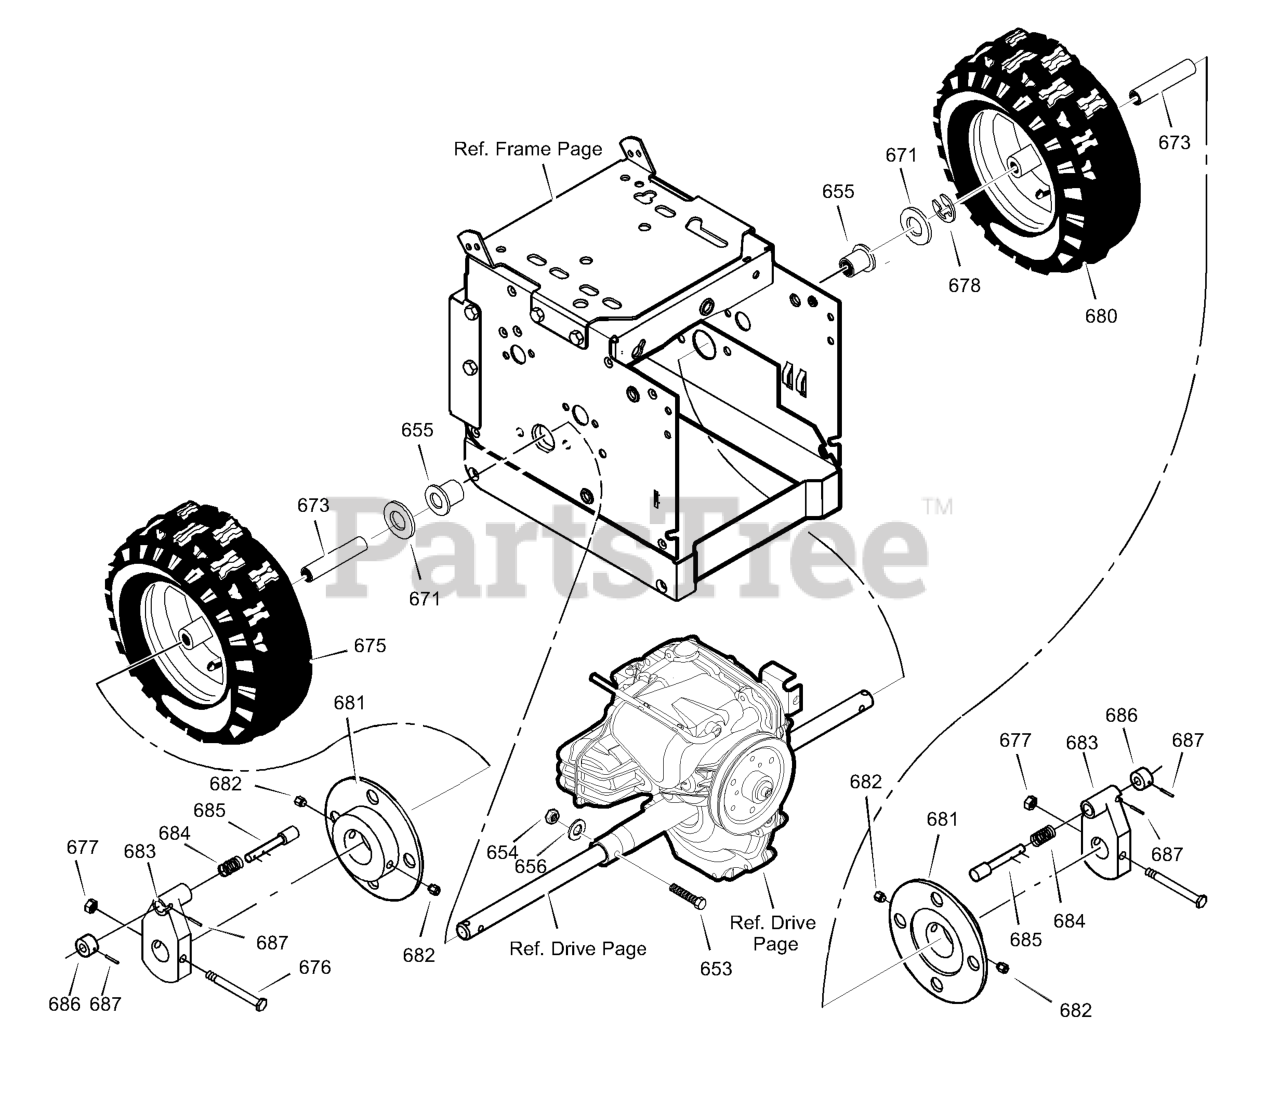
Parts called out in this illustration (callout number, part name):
653	SCREW, 1/4-20X1.75
654	NUT, 1/4-20 HEX NYLOCK
655	BEARING, AXLE
671	FLATWASHER
673	BUSHING, WHEEL, RIGHT
675	TIRE & RIM, RIGHT
676	SCREW, 1/4-20X2.25
677	NUT, 1/4-20 HEX NYLOCK
678	RING, RET
680	TIRE & RIM, LEFT
681	DISC,WHEEL
683	HUB, WHEEL LOCK
684	SPRING, COMPRESSION
685	PIN, LOCK
